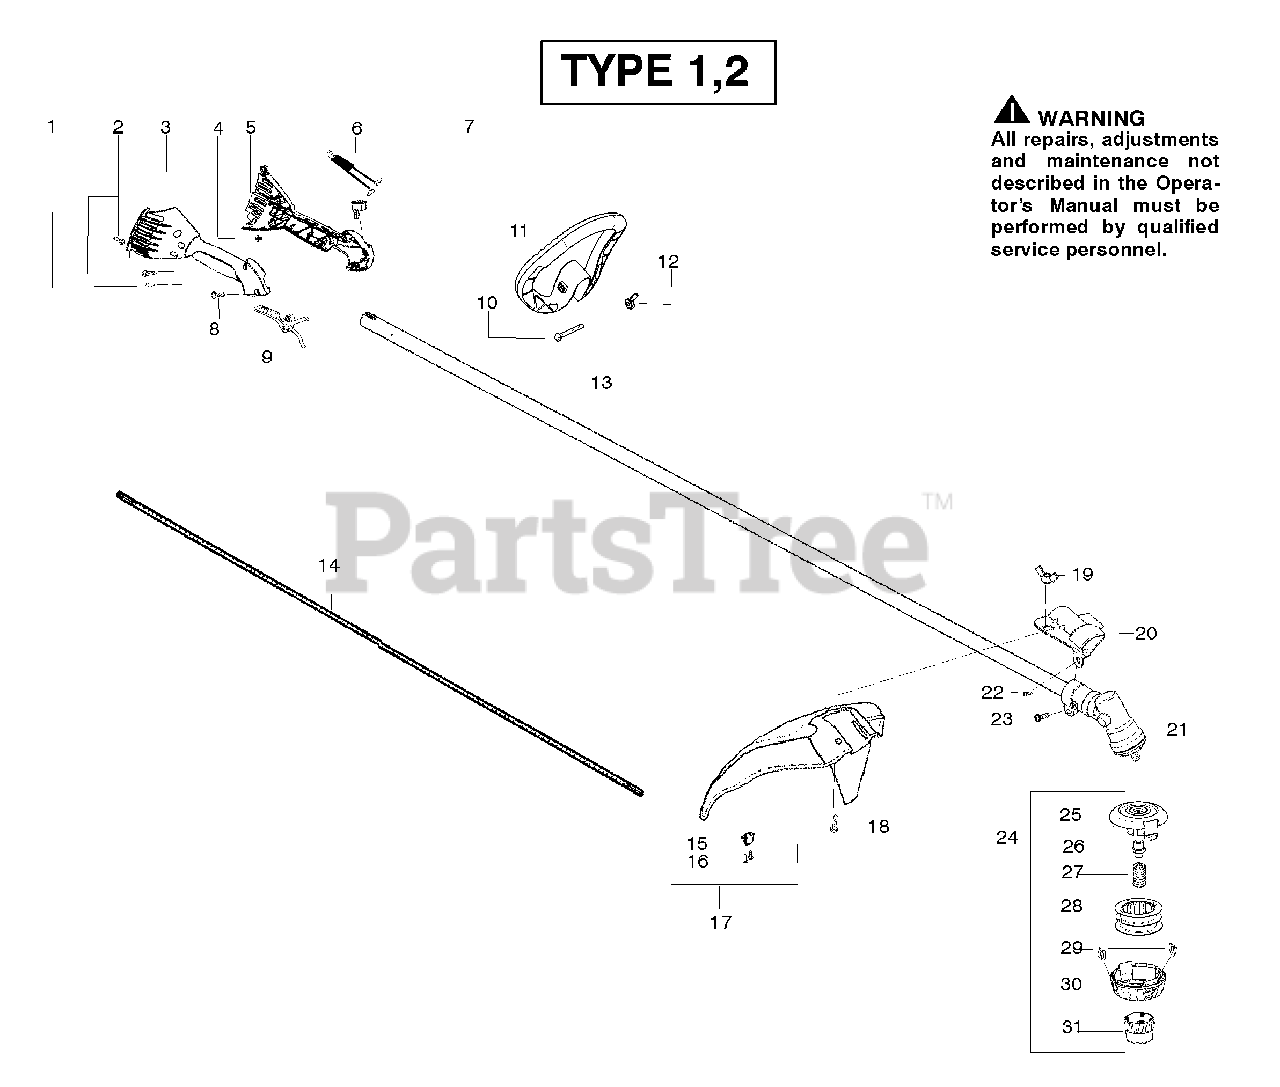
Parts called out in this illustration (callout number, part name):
1	Screw-alignment
3	Hsg.-Throttle right
4	Screw-Cable Retention
5	Hsg.-Left throttle
6	Assy-Wire
7	Kit-Switch
9	Lever-Throttle
11	Assy-Handle
12	Wingnut
13	Kit-Shaft
14	Shaft-Flex
15	Limiter-Line
17	Kit-Shield Assy.
19	Wingnut
20	Bracket-Shield
24	Assy-TNG VII
28	Accy-Wound Spool
29	Eyelet
30	Cover
